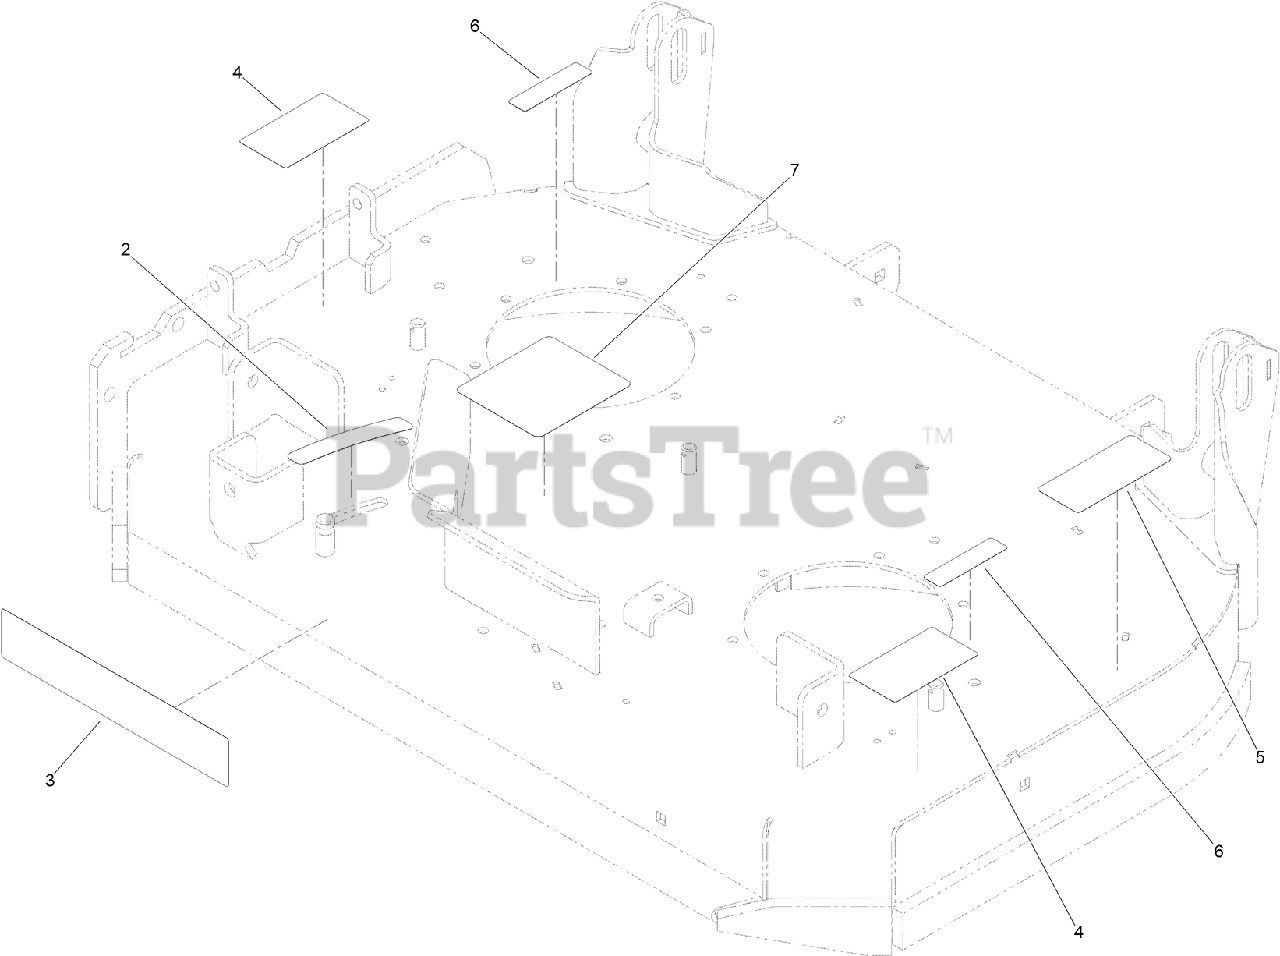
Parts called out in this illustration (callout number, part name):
2	DECAL-SETTING, BAFFLE
4	DECAL-DANGER
5	DECAL-TORQUE, BLADE BOLT
6	DECAL-DANGER
7	DECAL-ROUTING, BELT
